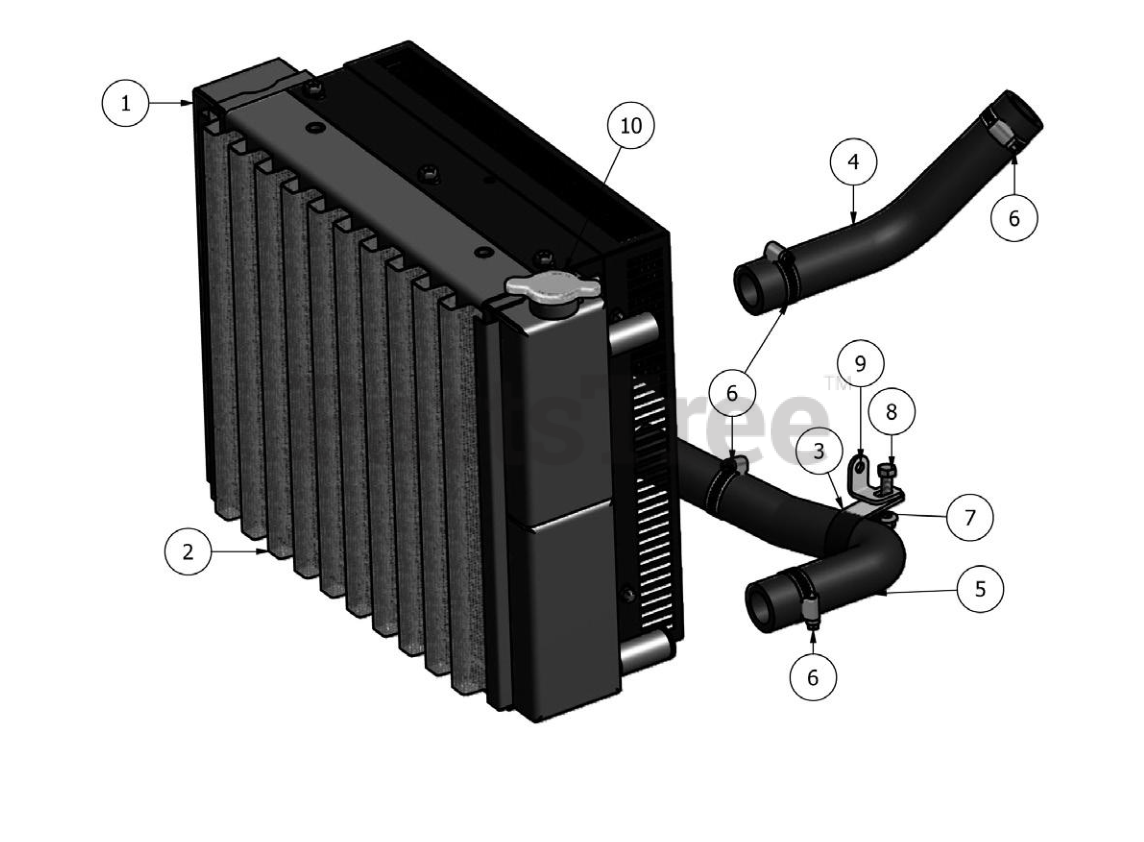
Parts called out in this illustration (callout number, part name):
1	Radiator- 28hp & 35hp Diesel Models
2	Radiator Screen-Diesel
3	Diesel Clamp 1 3/4" Vinyl
4	Top Radiator Hose for Diesel
5	Bottom Radiator Hose for Diesel
6	1 1/8" Hose Clamp
7	5/16" Flange Nut
8	5/16" x 3/4" Hex Bolt
9	Diesel Radiator Hose Clamp Bracket
10	Diesel Radiator Cap
